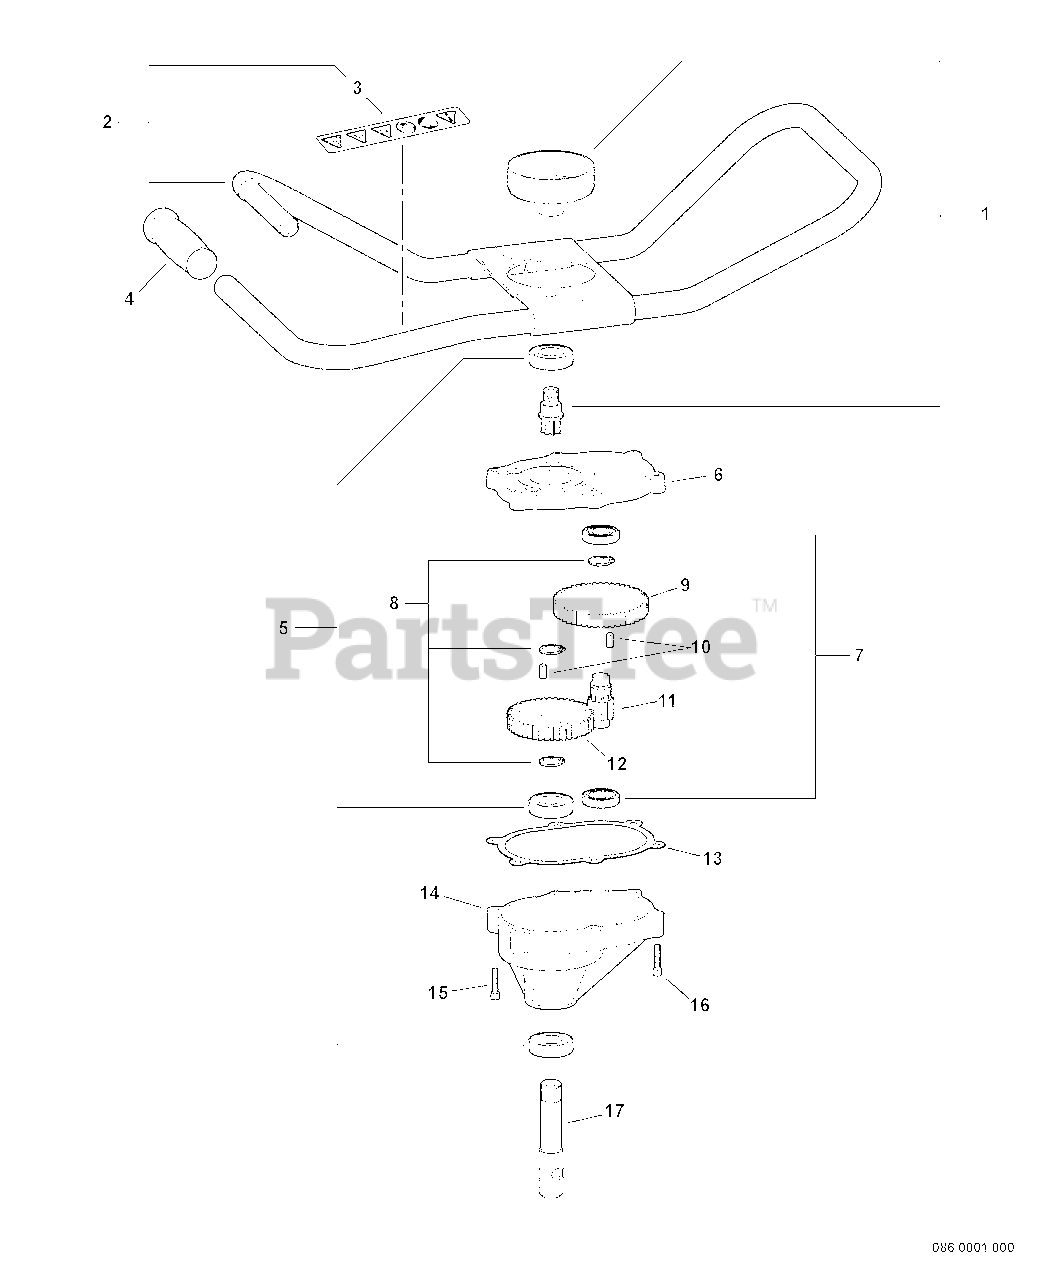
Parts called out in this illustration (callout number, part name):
1	CLUTCH DRUM KIT
2	HANDLE BAR ASSY
3	LABEL - CAUTION
4	GRIP, HANDLE
5	BEARING, BALL
6	CASE, GEAR - UPPER
7	BEARING, BALL
8	RING, RETAINING
9	GEAR - SPUR
10	PIN - LOCATING
11	GEAR - SHAFT
12	GEAR - SPUR
13	GASKET, GEAR CASE
14	CASE, GEAR - LOWER
15	BOLT - 1/4-20 X 2"
16	BOLT - 1/4-20 X 1-1/2"
17	DRIVESHAFT
